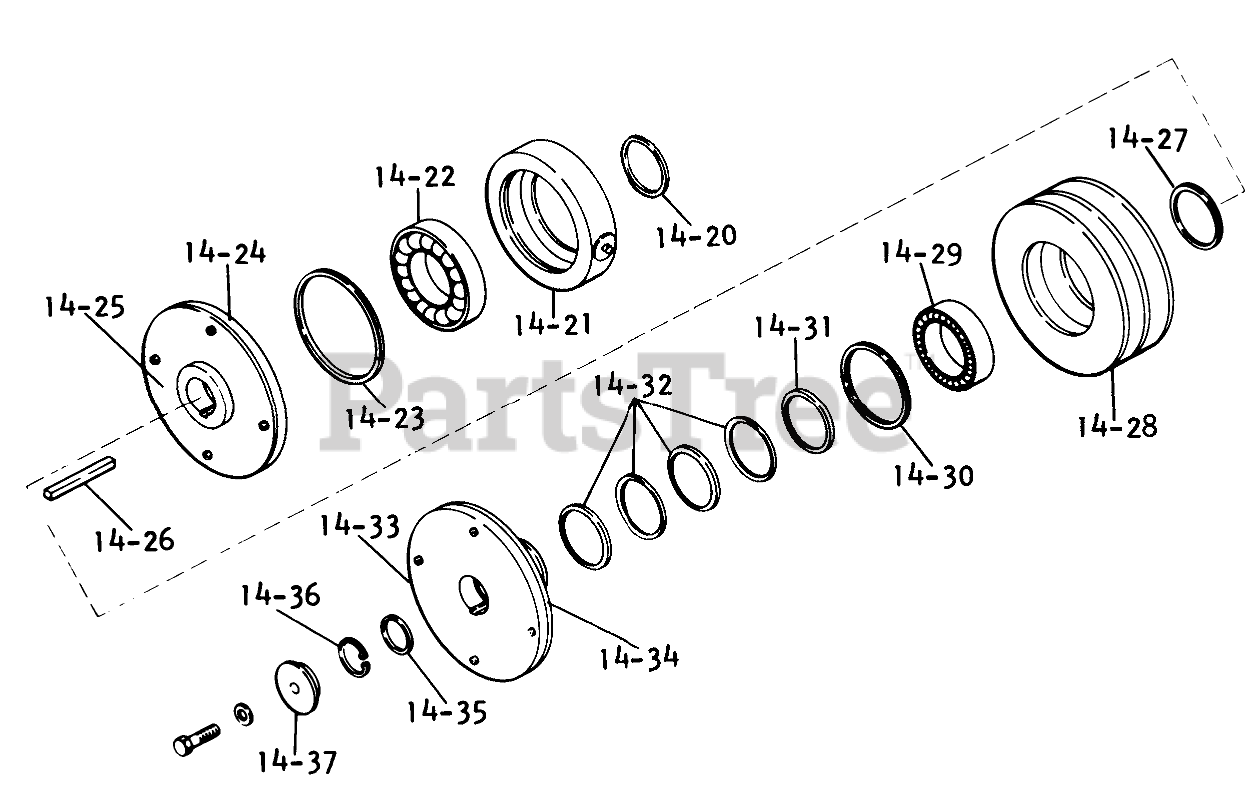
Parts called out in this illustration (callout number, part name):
14-20	RING EXTERNAL
14-21	ASSY COLLAR
14-22	BEARING
14-23	RING INTERNAL
14-24	ASSY CLUTCH PLATE
14-27	RING EXTERNAL
14-28	PULLEY CLUTCH
14-29	BEARING
14-30	RING INTERNAL
14-31	WASHER
14-32	SPRING WASHER
14-33	Assy-Outer Clutch
14-35	WASHER
14-36	INTERNAL RING
14-37	END CAP
14-38	ASSY HOOK
14-39	ASSY-CLUTCH BAR R
14-40	TRUNION
14-41	CLUTCH ROD
14-42	SPRING
14-43	Bushing
14-44	Washer
14-45	TURN BUCKLE NUT
14-46	Assy-Clutch Rod
14-47	ARM CLUTCH ENGAGE
14-48	BRACKET
14-49	ASSY CLUTCH HANDLE
14-51	Clutch Brake
14-53	Bracket-Brake
